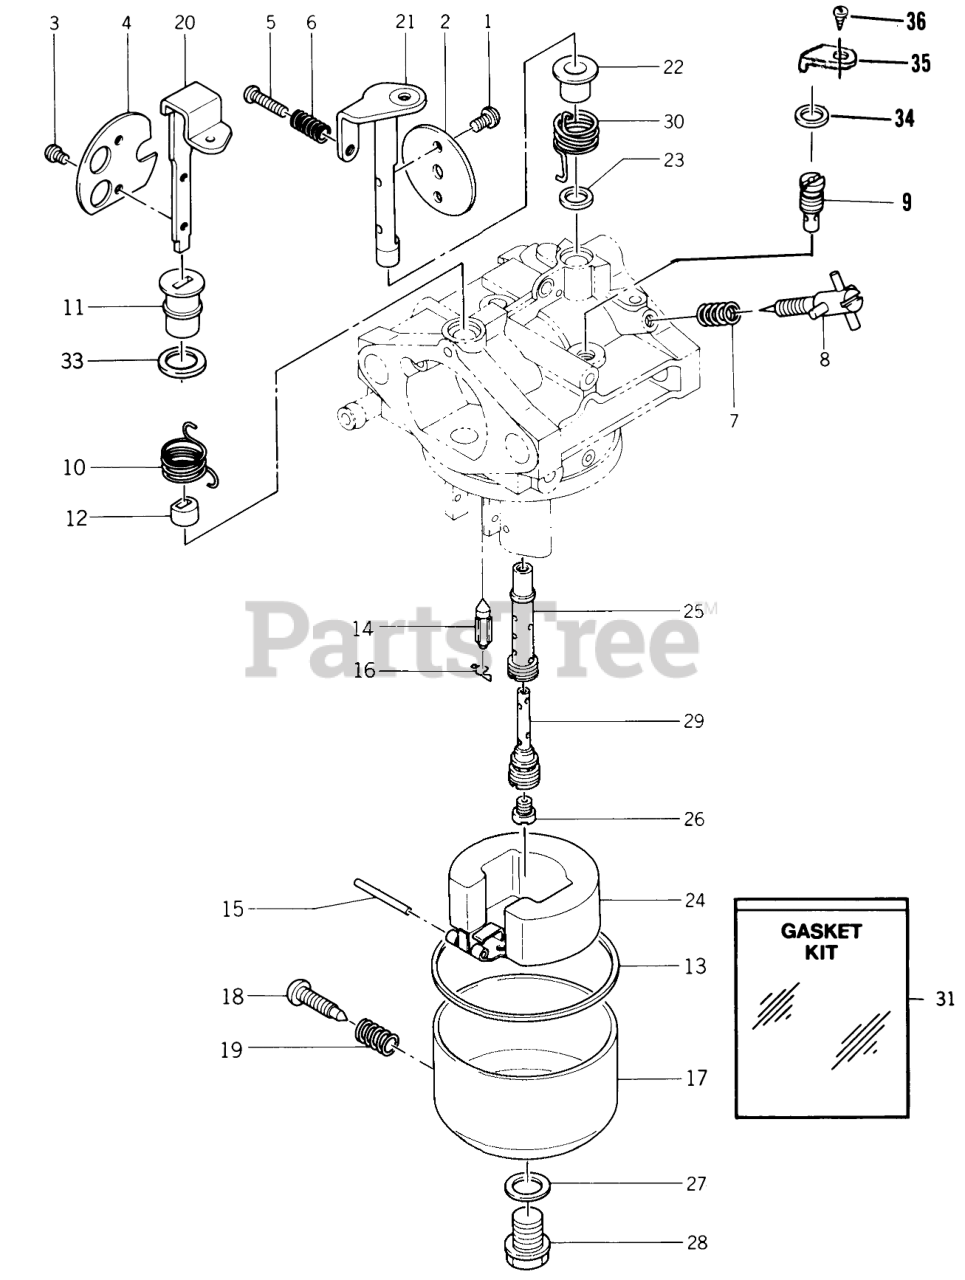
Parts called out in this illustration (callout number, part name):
1	SCREW-THROTTLE PLATE
2	VALVE THROTTLE
3	SCREW
4	VALVE CHOKE
5	SCREW
6	SPRING IDLE
7	SPRING
8	Adjuster Screw
9	JET-PILOT
10	SPRING
12	COLLAR
13	GASKET
14	NEEDLE VALVE ASSY
15	PIN-FLOAT
17	16020-2094 Float Chamber Assy (includes items 18 & 19)
18	SCREW-DRAIN
19	SPRING
20	SHAFT-CHOKE
21	Shaft-Throttle
22	RING BUSHING
23	RING-O
24	FLOAT
25	NOZZLE-MAIN
26	JET MAIN
27	GASKET
29	HOLDER-MAIN JET
30	Spring
31	Carburetor Gasket Set
34	O-RING
35	PLATE
36	Screw
